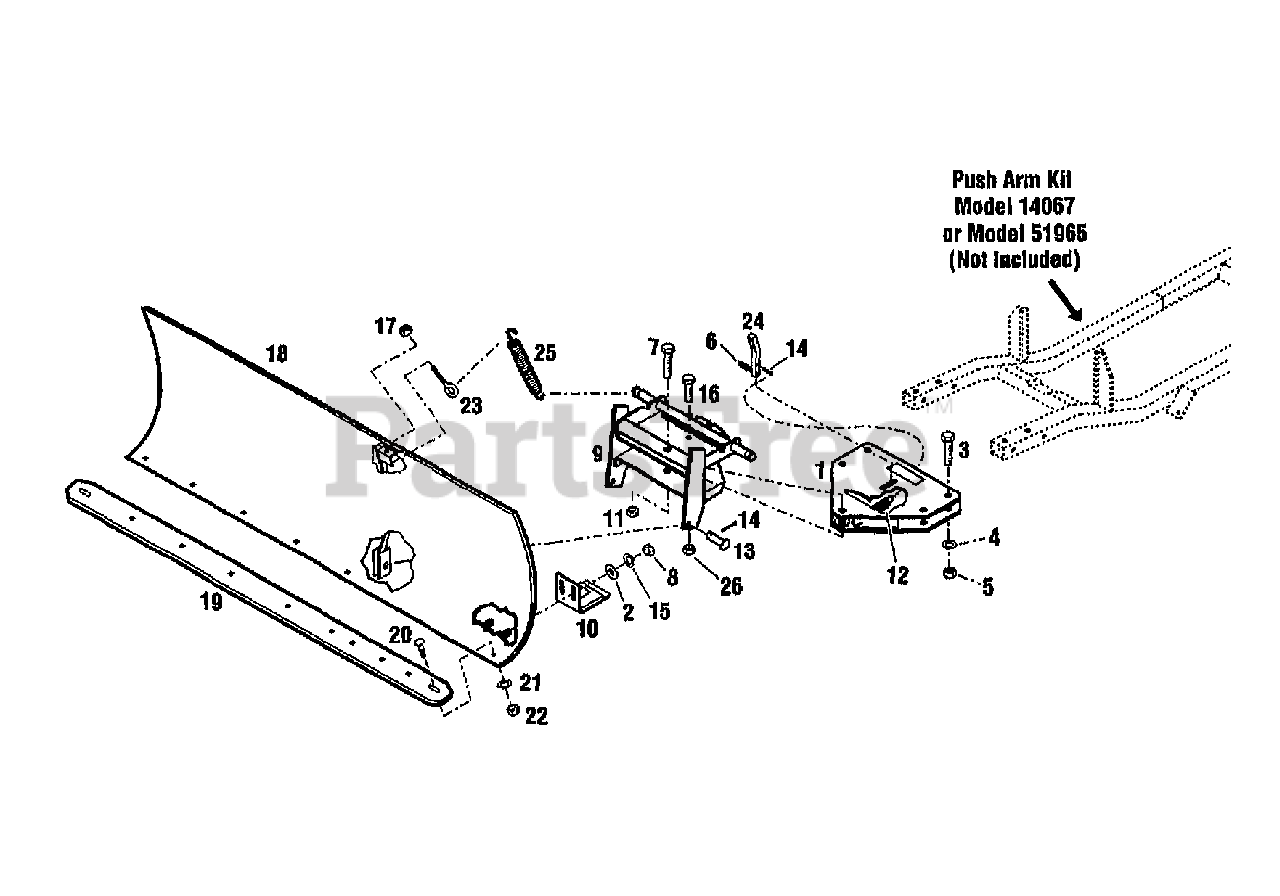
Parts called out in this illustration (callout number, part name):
2	WASHER-FLAT 3/8 SAE
3	SCR-HH 1/2-13X2.5 G5 ZP
4	WASHER-LK .5
5	NUT-TOP LOCK 1/2-13 ZP
6	PIN-DRIVE .125X1.0
7	SCR-HH 5/8-11X3.0 G5
8	NUT-HEX 3/8-16 ZP
10	SHOE-SKID
11	NUT-LOCK
12	SPRING
13	PIN-CLEVIS .5X1.06 ZP
14	PIN-COTTER .125 X .75 ZP
15	WASHER-LK .375 @ DEPL
16	SCR-HH 3/8-16X2.75 G5 ZP
17	NUT-TOP/LK 5/16-18 ZP
19	BLADE-SCRAPER
20	SCR-CARR 5/16-18X1.0 G2 ZP
21	WASHER-LK .312 ZP
22	NUT-HEX 5/16-18 ZP
23	BOLT-EYE 5/16-18X2.75 ZP
24	PIN-LATCH
26	NUT-LOCK 3/8-16
